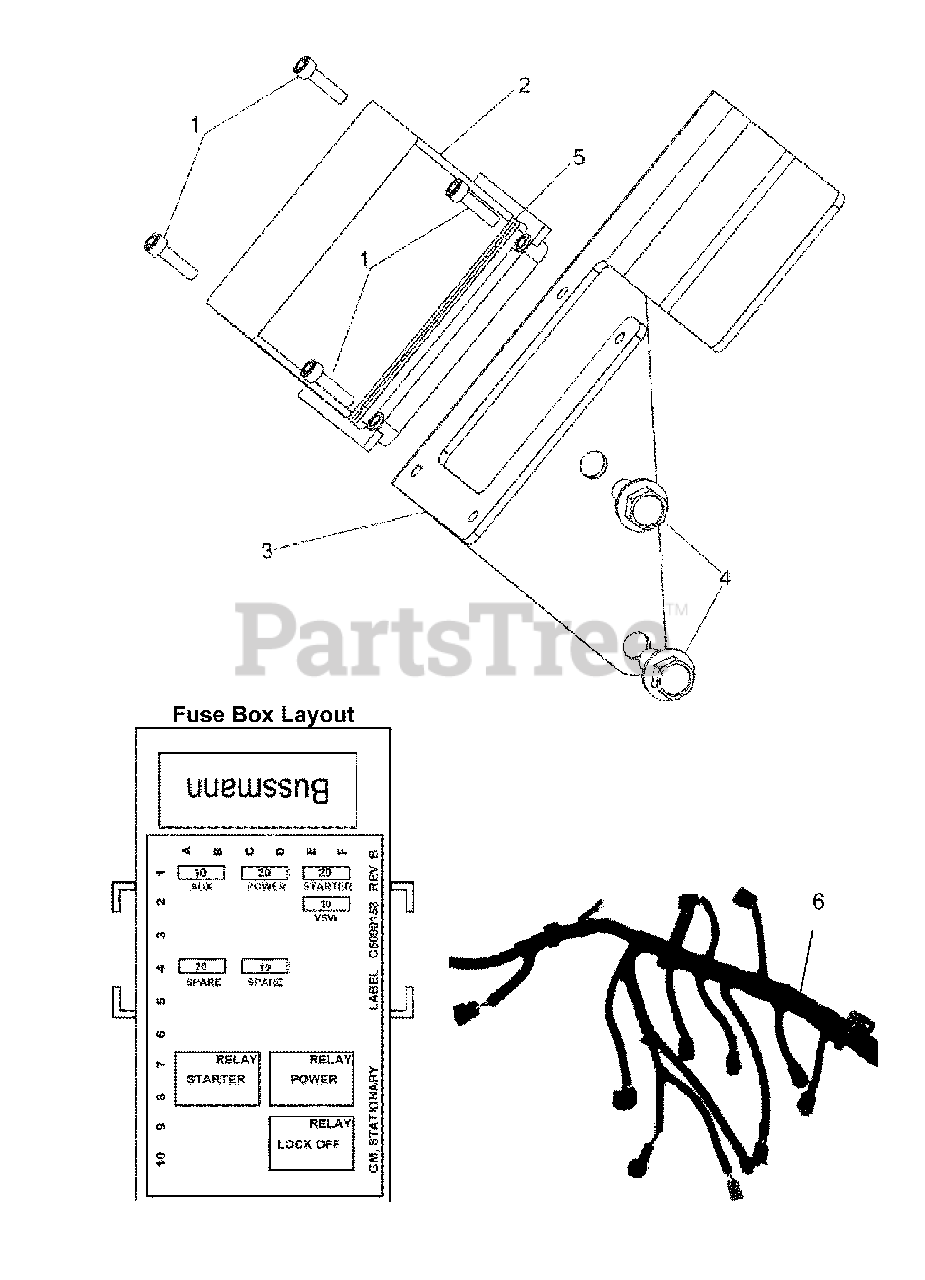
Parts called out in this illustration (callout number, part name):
1	SCREW
2	COVER-FUSE BOX
3	BRACKET
4	BOLT
5	SEAL
